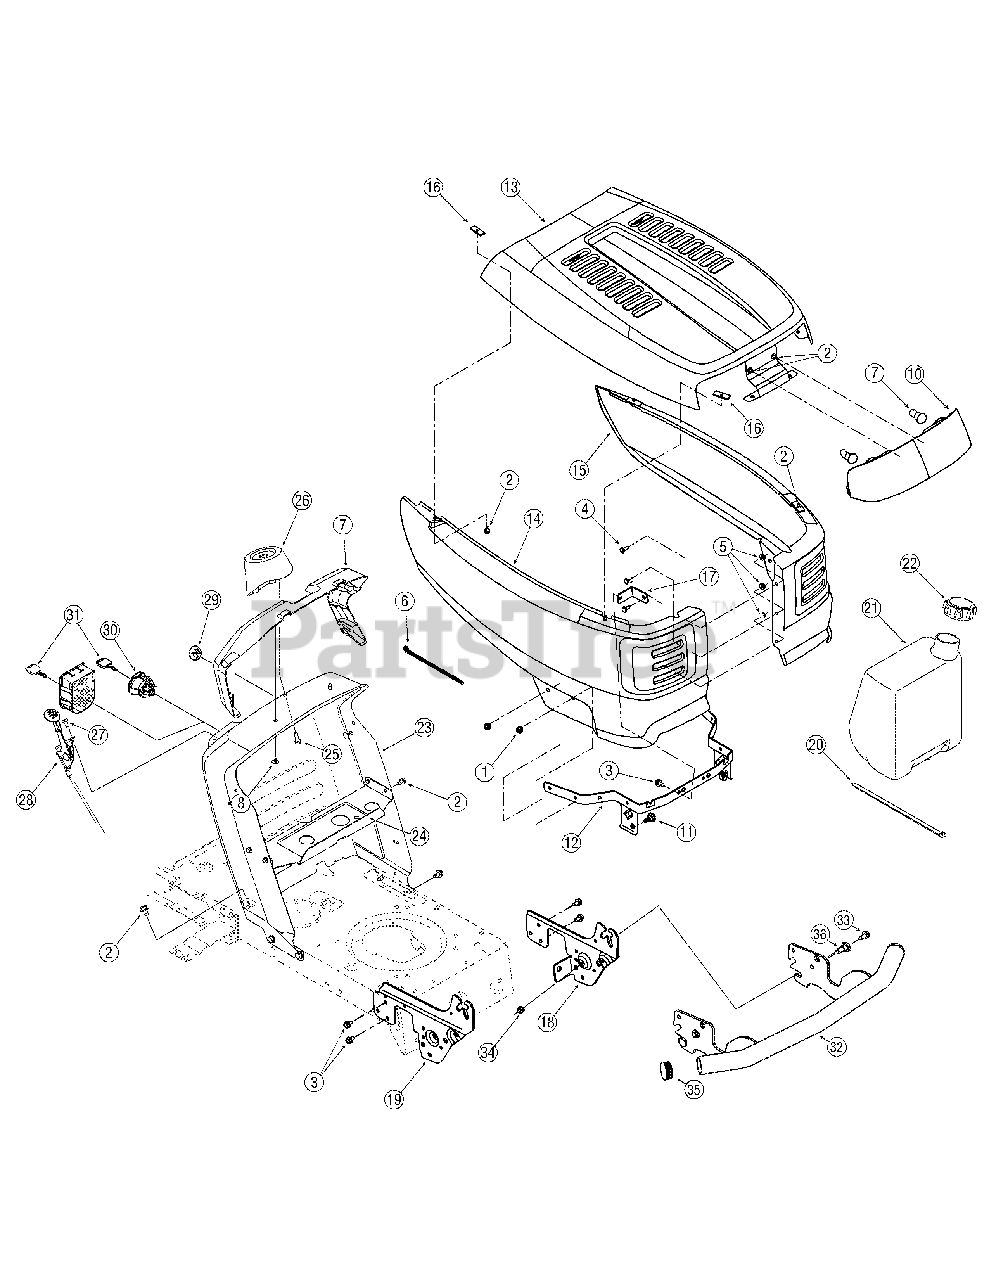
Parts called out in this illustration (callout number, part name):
1	Screw, 5/16-18, .375
2	Screw, 1/4-20, 0.500
3	Screw, 5/16-18, 0.625
4	Screw, 1/4-20, 0.620
5	Flange Lock Nut, 1/4-20
6	Cable Tie, 3/16 x .05 x 7.4
7	Headlamp, 12V
8	Ratchet Clip
9	Collar, Dash, 3-Style
10	Troy-Bilt Lens
11	Screw, Shldr, .43 x .29, 5/16-18
16	T-Style Hood Fastener
20	Cable Tie, 34.75
21	Fuel Tank, 1.5 gal.
22	Fuel Tank Cap
25	Screw, 1/4-15, .750
26	Support, Steering
27	Screw, 1/4-14, .500
28	Throttle/Choke Control, 25.0
29	Choke Plug
30	Module, Ignition Switch (No RMC)
30	Module, Ignition Switch (RMC)
31	Key
33	Screw, 5/16-12, 0.750
34	Flange Lock Nut, 3/8-16
35	Bumper Cap
36	Shoulder Bolt, 3/8-16
